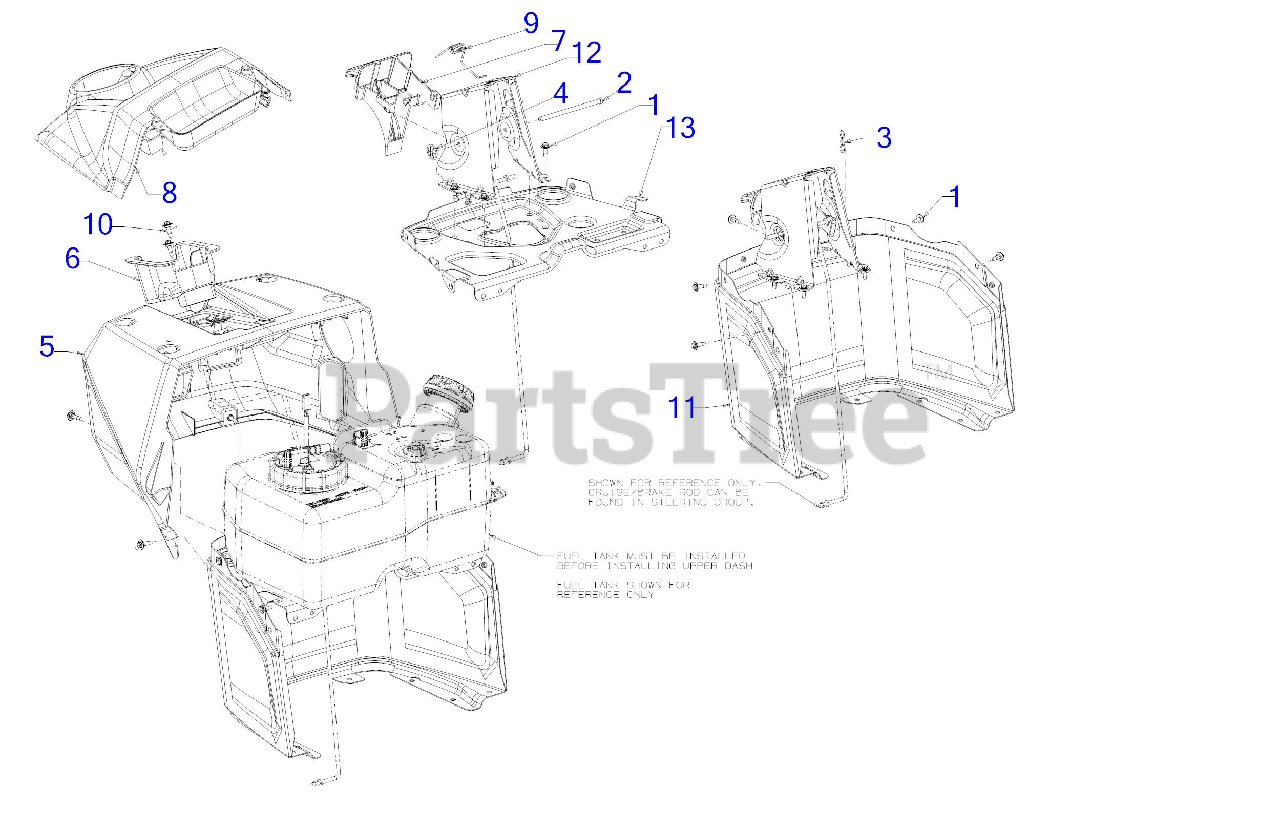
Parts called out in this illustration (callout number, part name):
1	SCREW M6-1 x .625
2	HINGE PIN .25 x 4.50
3	BOW TIE COTTER PIN 1/4-5/16
4	PUSH ON NUT
6	STEERING SHAFT BEARING
7	CRUISE/BRAKE DASH LEVER
8	UPPER DASH CAP
9	TORSION SPRING .330 ID
10	SHOULDER SCREW M6-1 .368 X.115
